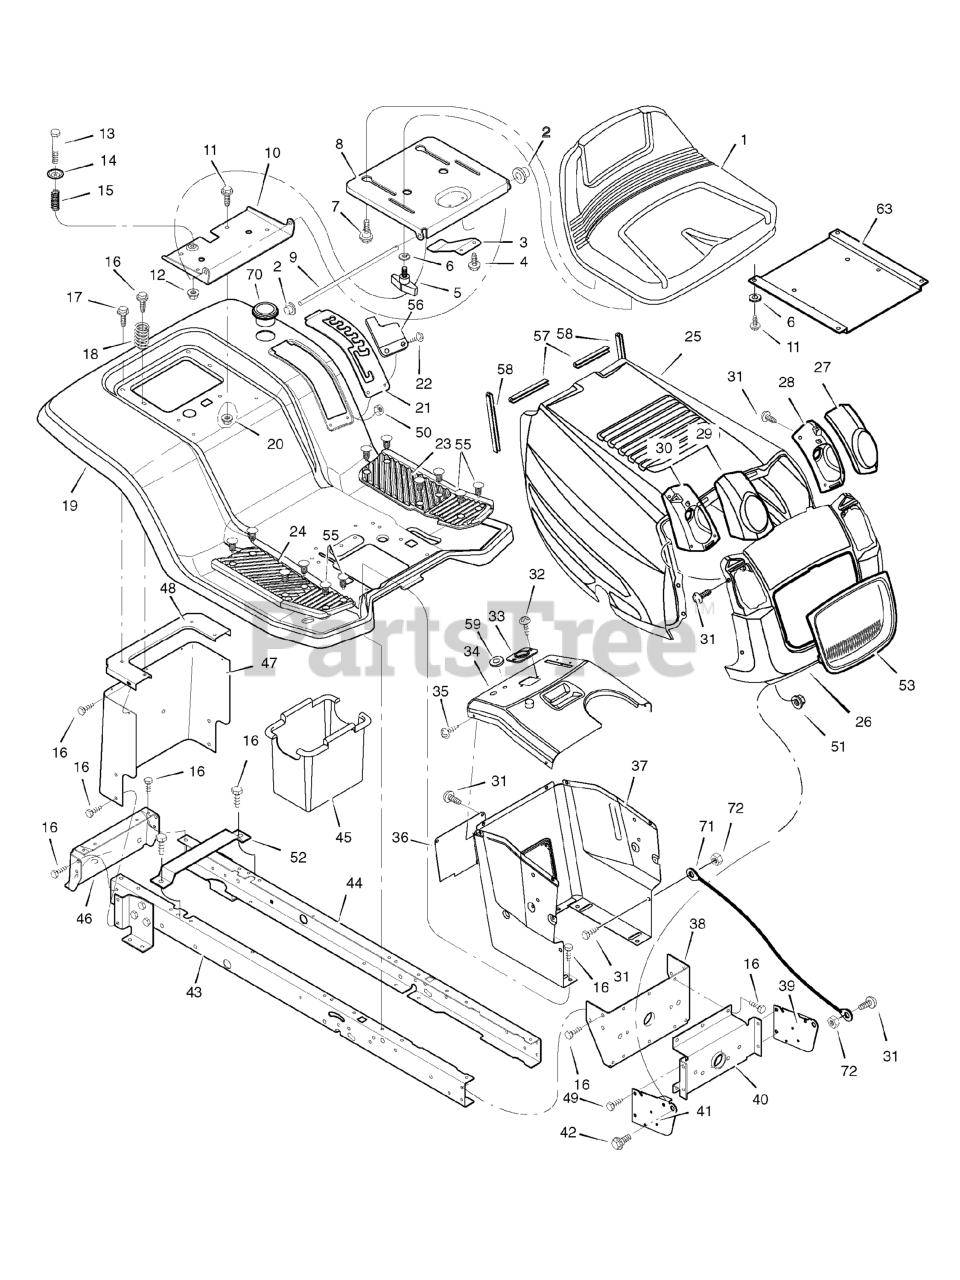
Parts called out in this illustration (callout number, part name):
2	Cap, Push 0n
5	Bolt, Wing
6	Washer
7	Bolt, Shoulder
8	Support, Seat
9	Rod, Pivot
10	Bracket, Pivot
11	Bolt
13	Bolt, Shoulder
19	Deck, Seat
20	Nut
21	Plate, Index
23	Mat, Left
24	Mat, Right
25	Hood
27	Lens, Left
28	Housing, Left Headlamp
29	Lens, Right
30	Housing, Right Headlamp
33	Bearing, Steering
36	Panel, Access
37	Support, Dash
38	Support, Rear Hanger
39	Support, Left Grille
40	Axle, Hanger
41	Support, Right Grille
42	Bolt, Shoulder
43	Frame, Right
44	Frame, Left
45	Container, Battery
46	Plate, Hitch
47	Plate, Rear
48	Top, Rear Plate
49	Bolt, Shoulder
51	Nut
52	Bracket, Battery Support
53	Insert, Grille
55	Fastener, Panel
56	Cover, Detent
57	Trim, Hood (3.75")
58	Trim, Hood (6.5")
59	Grommet, Parking Brake
63	Assembly, Plate Seat
70	Holder, Cup
